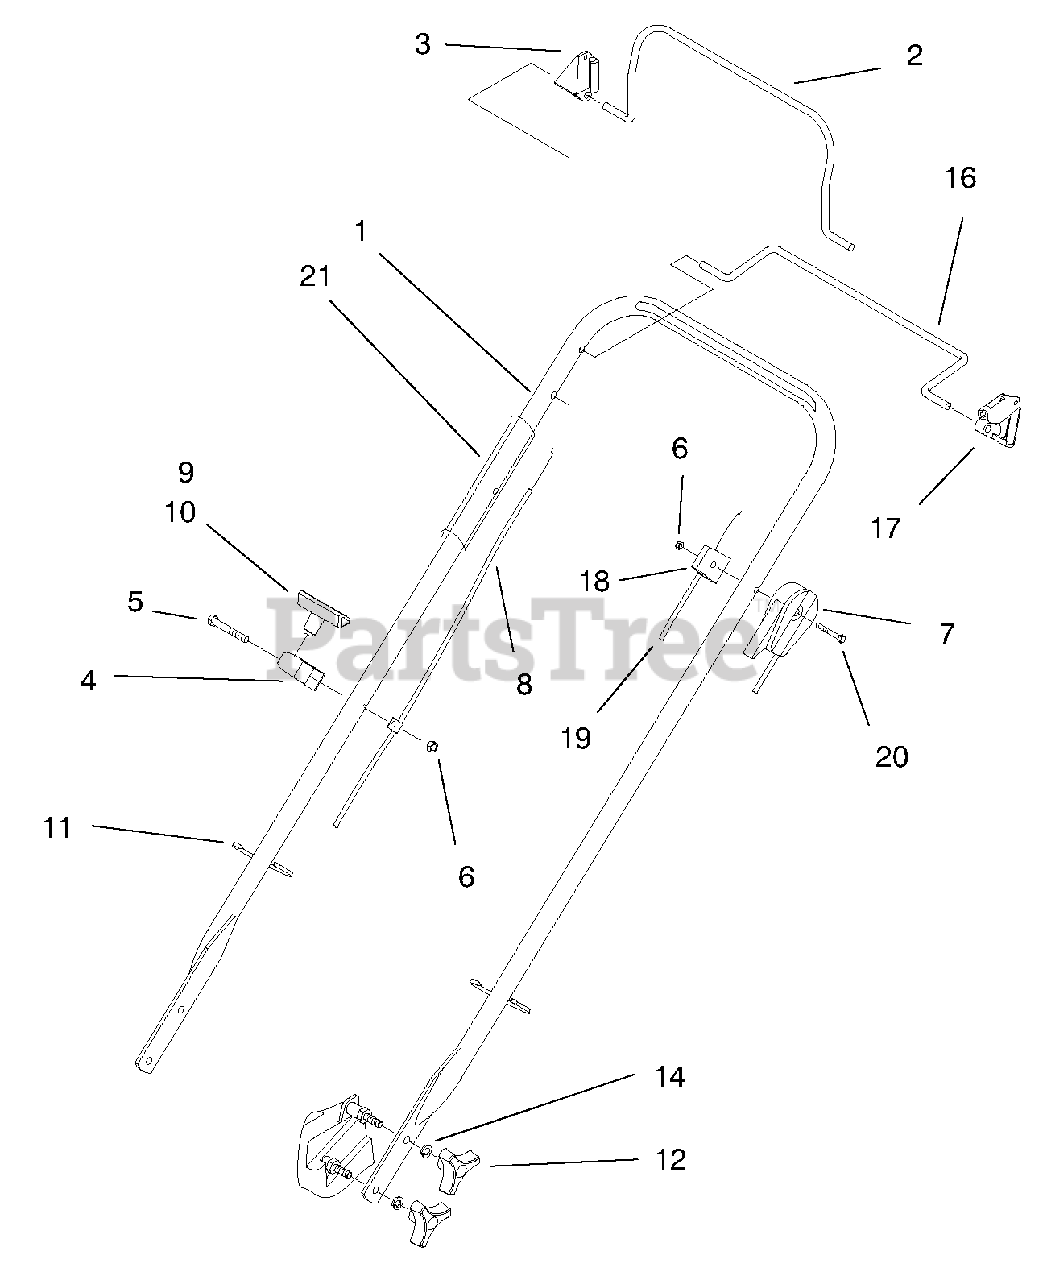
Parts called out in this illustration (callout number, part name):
2	Bail-Fly Wheel Brake
3	Stop-Pivot
4	Guide-Rope
5	Screw-HH
6	Nut-Lock Insert
7	Cable-Throttle
8	Cable-Brake
9	Clip-Rope Insert
10	Handle-Starter
11	Tie-Cable
12	Knob
14	Washer-Lock
16	Bail-Control
17	Stop-Pivot
18	Anchor-Cable
19	Cable-Traction
20	Screw-HH
21	Decal-Operation
